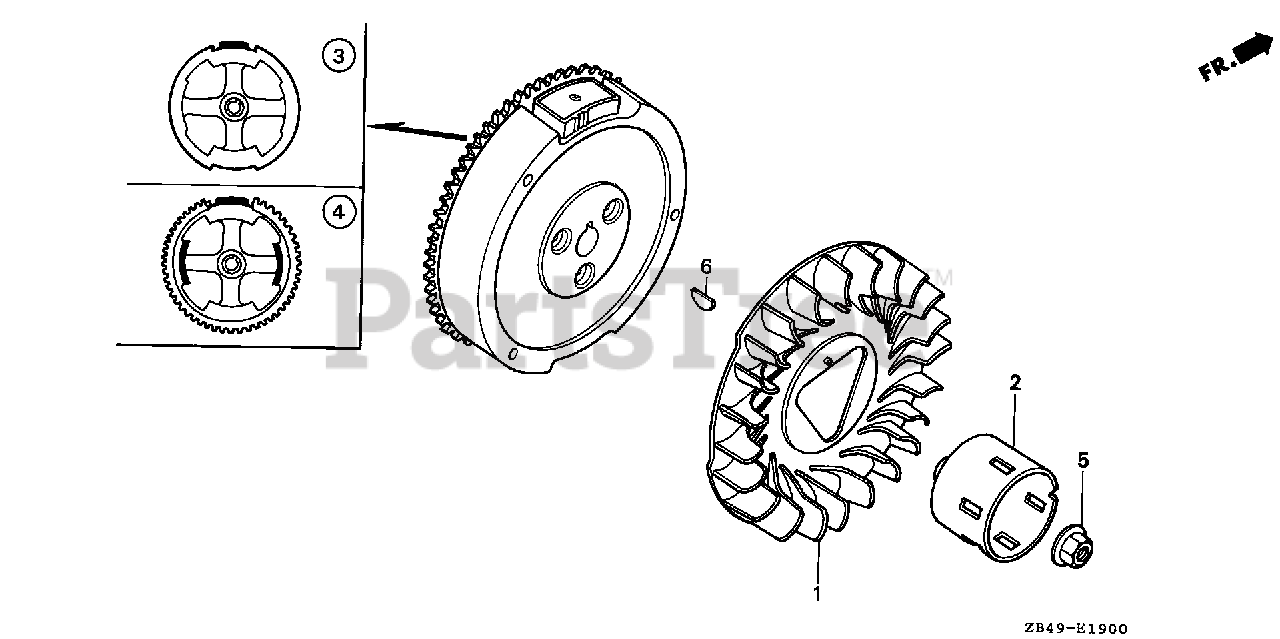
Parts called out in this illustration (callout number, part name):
1	FAN, COOLING
2	PULLEY, STARTER
4	FLYWHEEL (4POLE)
5	NUT, SPECIAL (16MM)
6	KEY, SPECIAL WOODRUFF (25X18)
